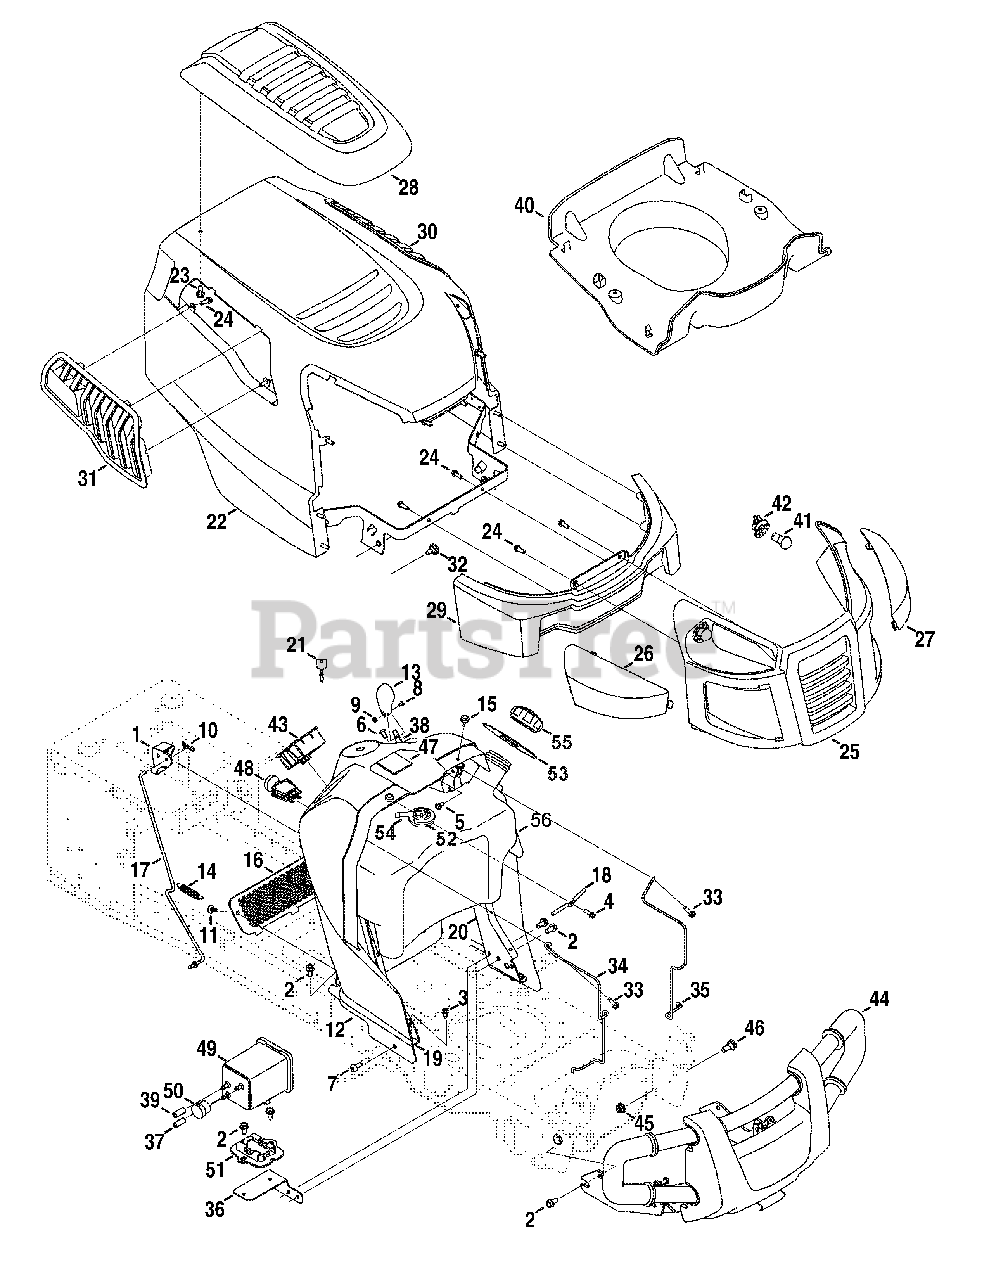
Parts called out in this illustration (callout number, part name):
1	Dash Lever
2	Taptite Screw, Lock Washer, 5/16-18:.750
3	Taptite Screw, Lock Washer, 1/4-20:0.500
4	Hi-Lo Screw, Lock Washer, 1/4-15:0.750
5	Screw, Lock Washer, 1/4-14:0.625
6	Screw, 1/4-14:0.625
7	Taptite Screw, 5/16-18:0.750
8	Machine Screw, #8-32:0.375
9	Hex Nut, #8-32:GRA
10	Bow-tie Cotter Pin
11	Ratchet Clip:.250 DIA
13	Control Knob
14	Extension Spring, .500 DIA X 2.733 LG
15	Bumper
16	Accessory Net
17	Control Rod Latch
18	Lever Rod
19	RH Dash Support Plate
20	LH Dash Support Plate
21	Keys (Set of 2)
22	Hood Assembly
23	Hi-lo Screw, Lock Washer, 1/4-15:0.50
24	Screw, Lock Washer, 1/4 DIA:.750
26	RH Lens
27	LH Lens
28	Hood Scoop
29	Lower Grill
30	LH Hood Scoop
31	RH Hood Scoop
32	Shoulder Screw, .43X.29:TT:5/16-18
33	Taptite Screw, 1/4-20:0.750
34	RH Tank Support Rod
35	LH Tank Support Rod
36	Carbon Canister Mounting Bracket
37	Fuel Hose
38	Throttle/Choke Control
39	Fuel Hose
40	P-Style Plen
41	Miniature Lamp, 12V
42	Lamp Socket
43	Switch Key Module
44	Guard Assembly
45	Flangelock Nut, 3/8-16
46	Shoulder Bolt, .496 x .336:3/8-16
47	Hour Meter
48	PTO Switch
49	Carbon Canister
50	Canister Vent Filter
51	Canister Adaptor Bracket
52	Rubber Gromet
53	Fuel Tank Gasket
54	Rollover Valve
55	Fuel Cap
56	Fuel Tank Assembly (Incl. Ref No. 52 - 55)
